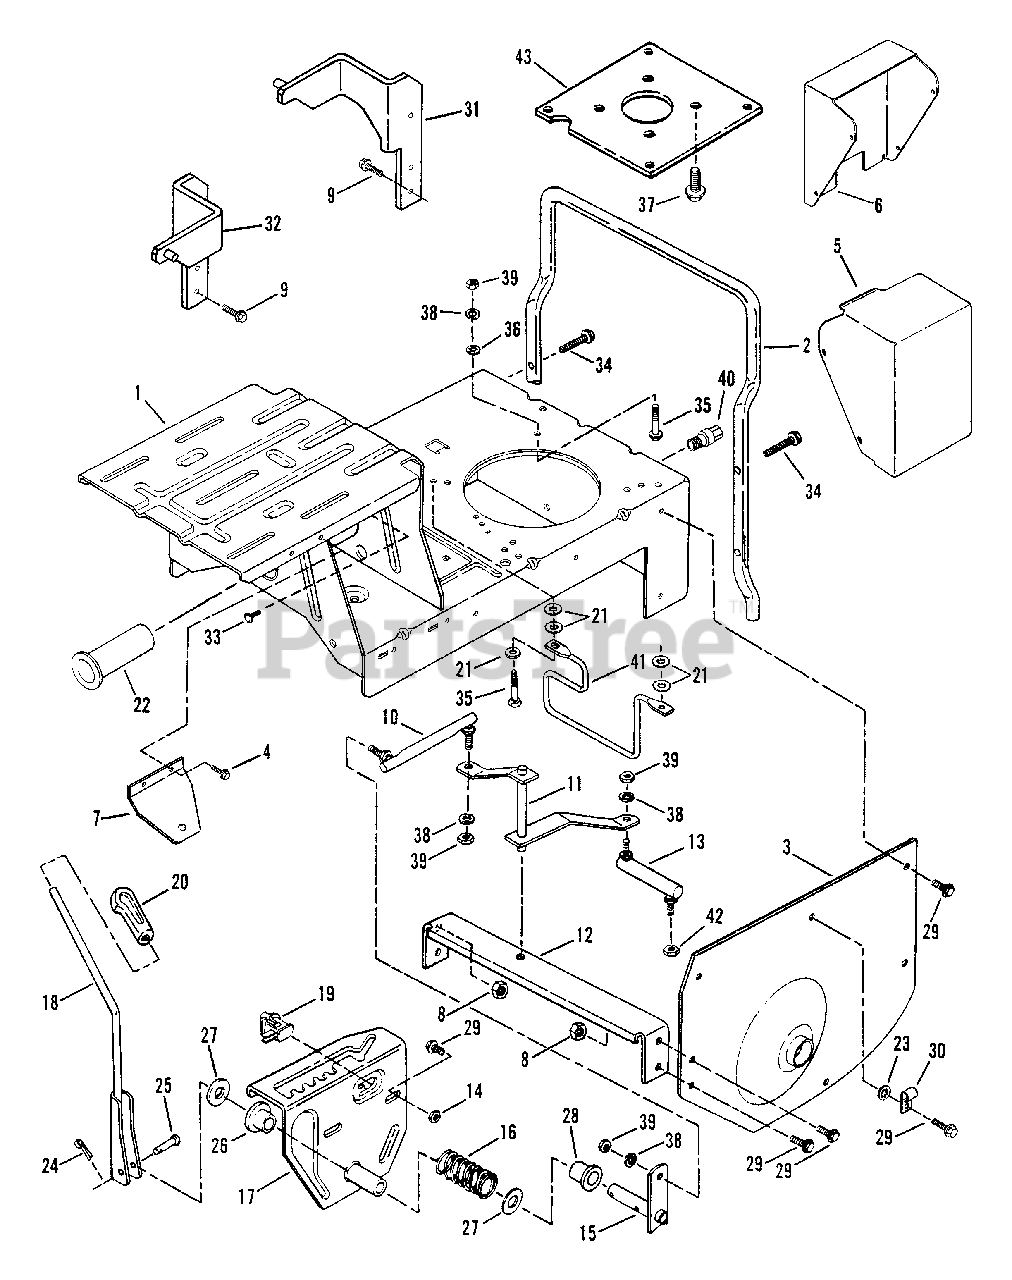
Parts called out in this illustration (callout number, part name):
1	CASE, Main
2	BUMPER, Rear (42" Models)
3	FENDER, Left Hand
4	SCREW, 1/4-20 x 1/2" Self-Tapping
5	COVER, Battery (42" Models)
6	COVER, Switch
7	PLATE, Choke (42" Models)
8	NUT, 5/16-18 Hex Flange Lock
9	SCREW, 5/16-18 x 1" Self-Tapping
10	LINK, Shift (Long)
11	ARM, Shift
12	BRACE, Cross
13	LINK, Shift (Short)
14	NUT, 5/16-18 Hex
15	ARM, Shift Handle
16	SPRING, Shift Handle
17	DETENT,Shift
18	HANDLE, Shift
19	SWITCH, Seat
20	KNOB, Shift Handle
21	WASHER, 5/16 Flat
22	BUSHING, Pilot
23	WASHER, 5/16 Internal Tooth Lock
24	PIN, 3/32 x 3/4" Cotter
25	PIN, 1/4 x 1-3/4" Tapered Clevis
26	BUSHING, Nylon
27	WASHER, Thrust
28	BUSHING, Nylon
29	SCREW, 5/16-18 x 5/8" Self-Tapping
30	CLIP, Wire
31	DECK WING, Rear (Right)
32	DECK WING, Rear (Left)
33	FASTENER, Ratchet
34	SCREW, 5/16-18 x 1-1/2" Self-Tapping
35	SCREW, 5/16-24 x 1" Hex Head Cap
36	RETAINER, 5/16 Bolt
37	SCREW, 3/8-16 x 1" Self-Tapping
38	WASHER, 5/16" Split Lock
39	NUT, 5/16-24 Hex
40	ASSEMBLY, Oil Drain
41	GUIDE, Belt (42" Models)
42	NUT, 5/16-24 Hex Flange Lock
43	PLATE, Engine
